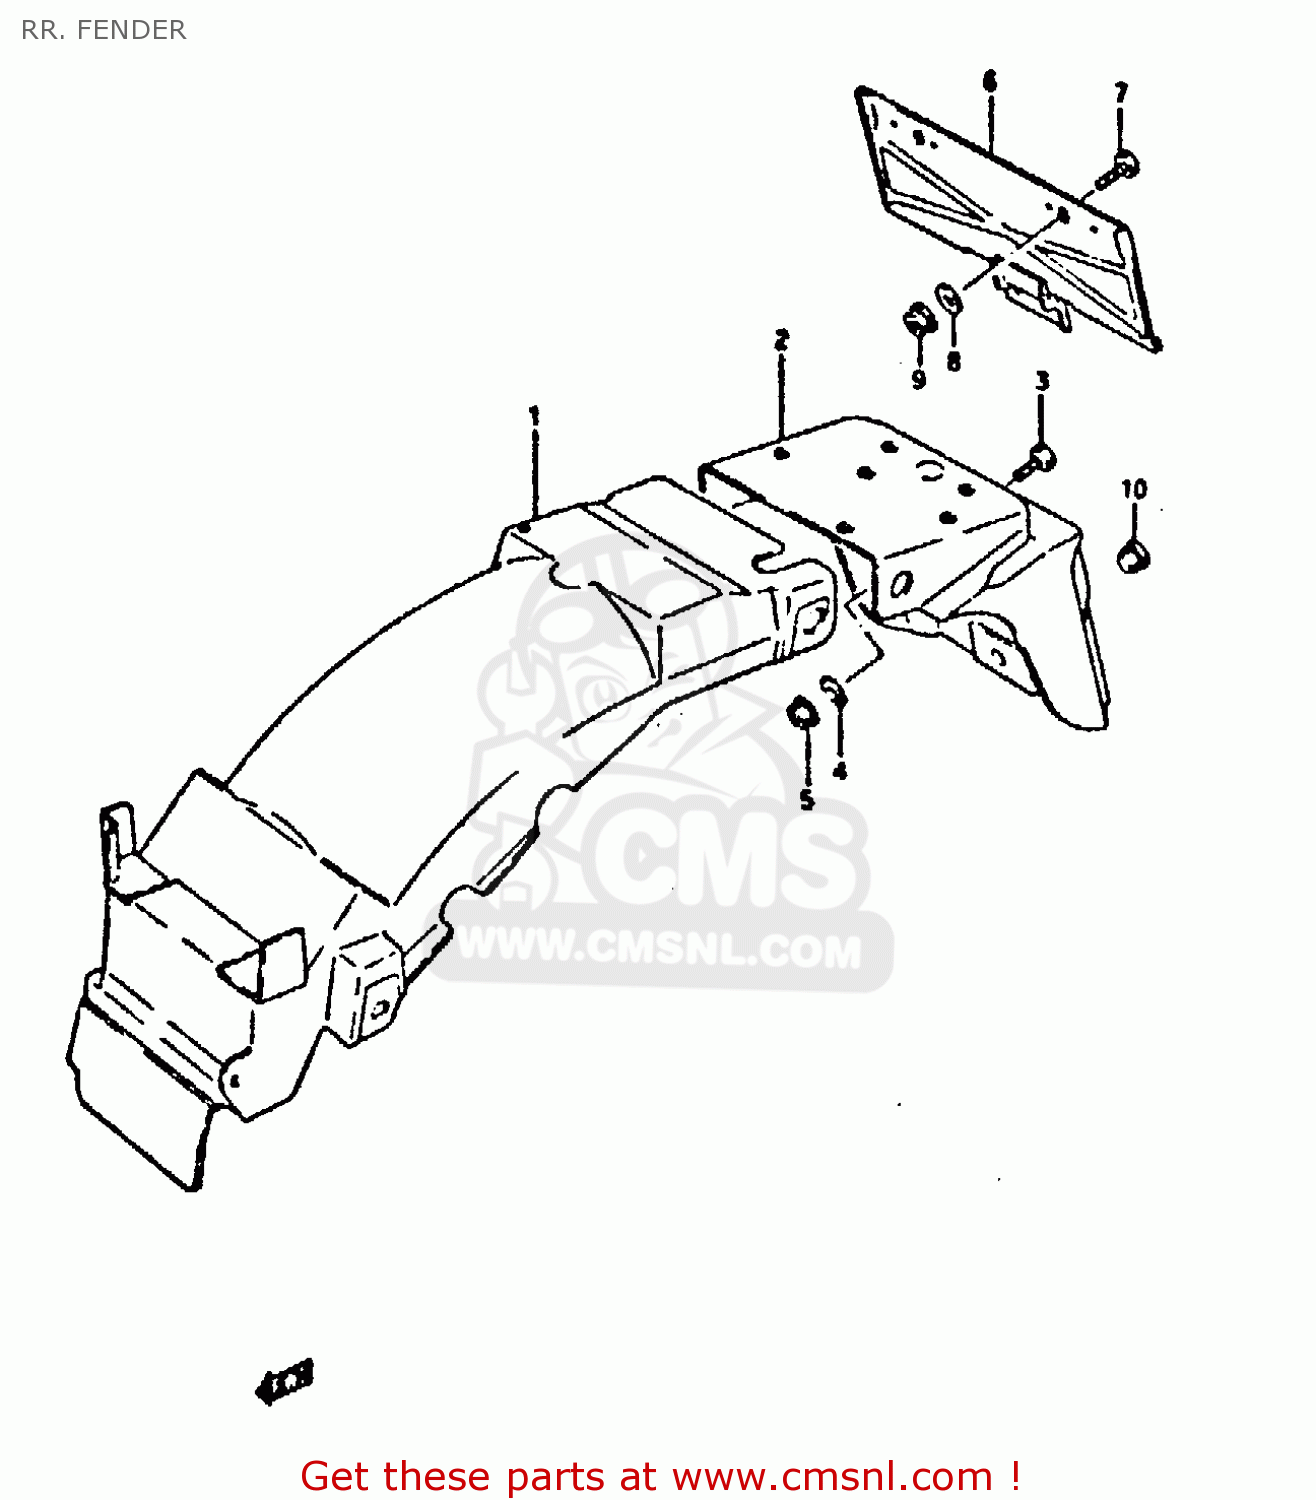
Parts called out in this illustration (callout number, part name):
1	BODY,REAR FENDE
2	BODY, REAR FENDER
3	BOLT
4	WASHER
5	NUT
6	HOLDER,RR LICENSE PLATE
7	BOLT
8	WASHER
9	NUT
10	CUSHION
